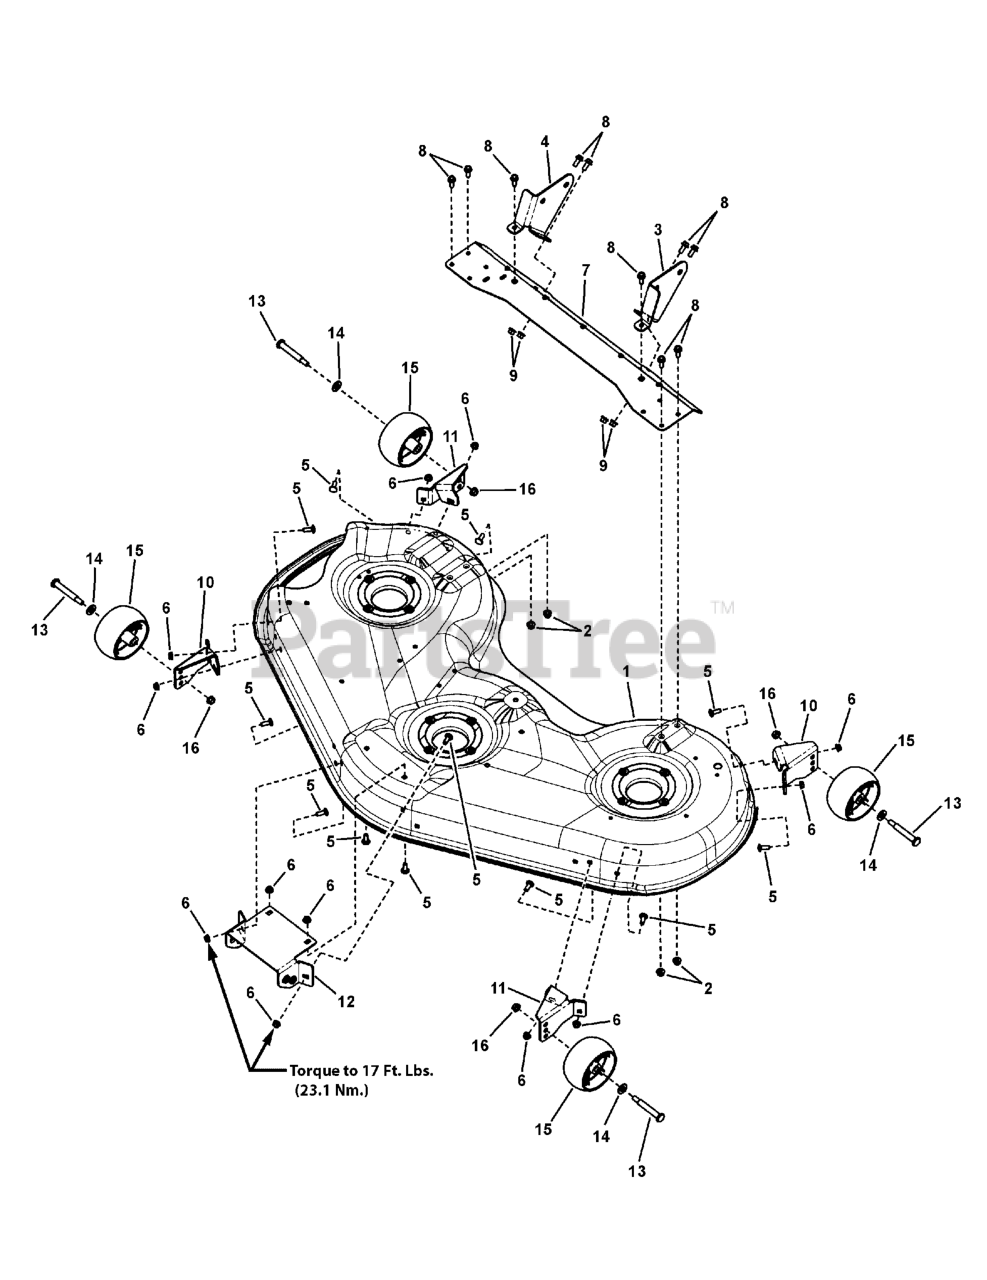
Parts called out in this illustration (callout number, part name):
1	HOUSING, 52" Mower
2	NUT, Hex Flange Whiz Lock, 5/16-18
3	BRACKET, L.H. Rear
4	BRACKET, R.H. Rear
5	BOLT, 5/16-18 x 7/8" Round Head Short Square Neck, GR 5, Black
6	NUT, 5/16-18 Hex Flange Lock, Small - Black
7	SUPPORT, Rear Cross
8	SCREW, 5/16-18 x 1" Hex Washer Head Self-Tap, Black
9	NUT, 5/16-18 Hex Flange Nyloc
10	BRACKET, Gauge Wheel, LH
11	BRACKET, Gauge Wheel, RH
12	HITCH, Front
13	SHOULDER BOLT, 3/8-16 x 3.41" .750 Thread Yellow
14	WASHER, 1/2" Flat (0.51 ID x 1.00 OD x .10 Thick) Black
15	GAUGE WHEEL, Black Poly 5" Dia.
16	NUT, 3/8-16 Hex Flange Esna, Black
